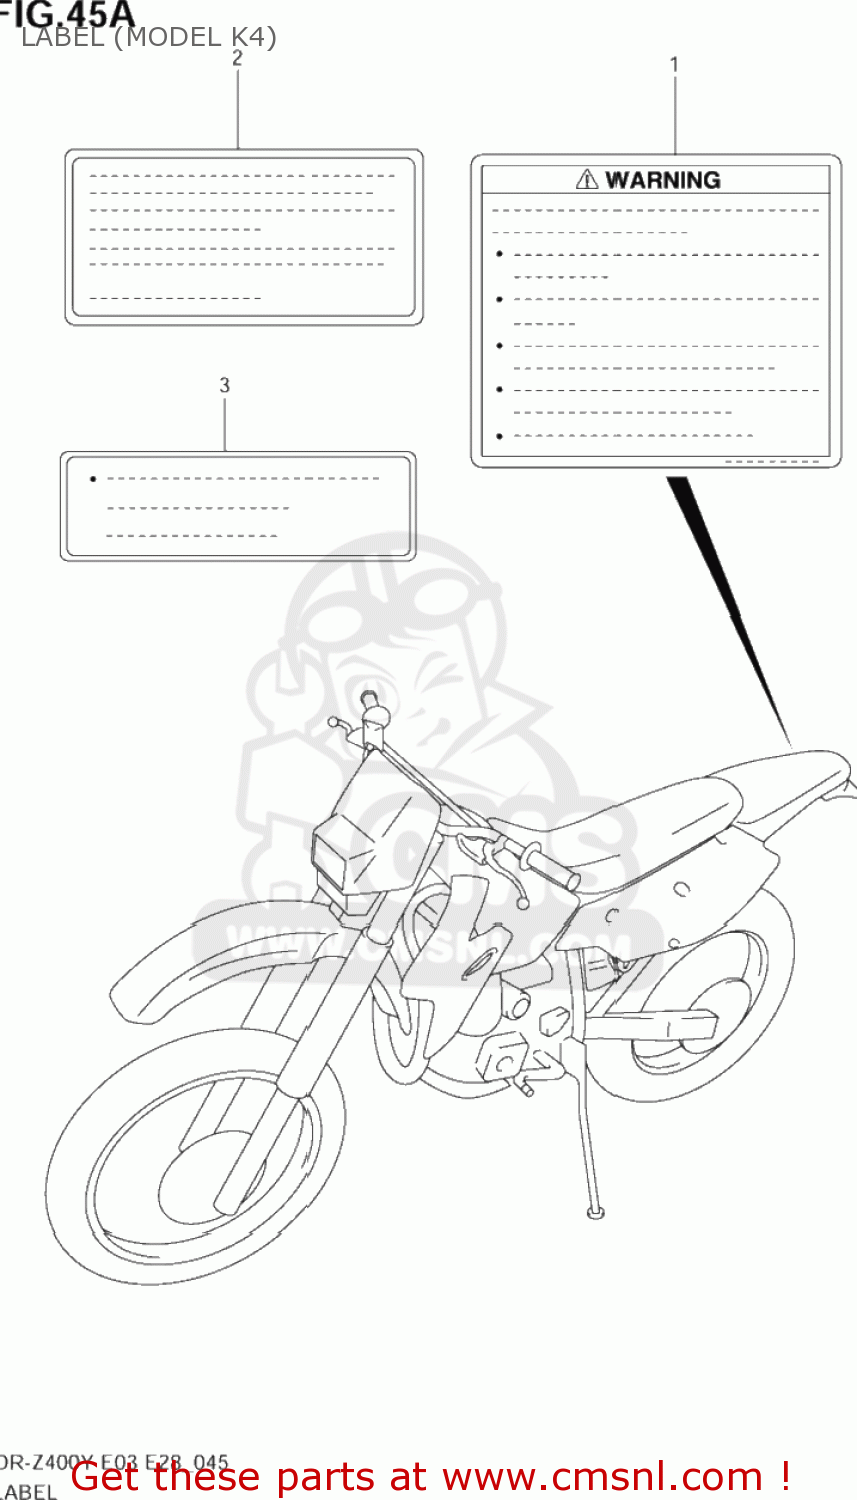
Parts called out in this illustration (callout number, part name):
1	LABEL,GENERAL WARNING
2	LABEL,MANUAL NOTICE
3	LABEL,FUEL INFORMATION
4	MANUAL,OWNER'S
